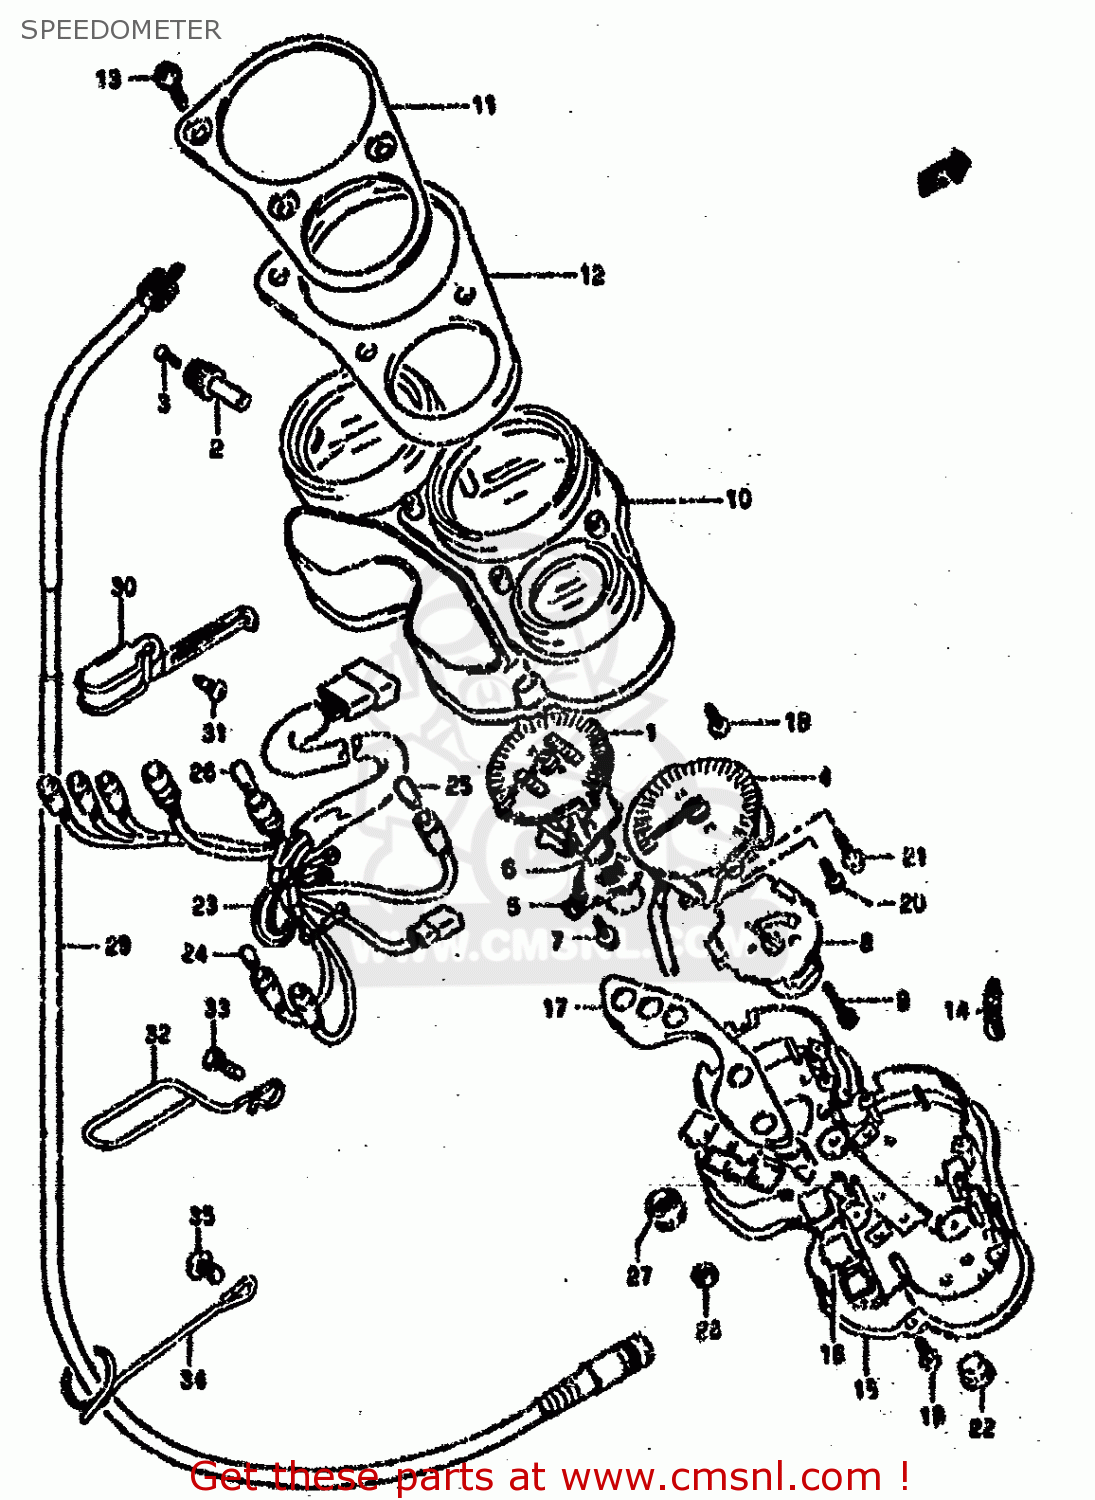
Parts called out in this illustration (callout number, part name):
1	SPEEDOMETER
2	KNOB,TRIP
3	ROTOR,SPEED
4	TACHOMETER
5	GEAR BOX,SPEEDOMETER
6	O RING
7	SCREW
8	METER,TEMPERATURE
9	SCREW(3X22)
10	HOOD
11	PANEL,METER
12	CUSHION
13	SCREW
14	CLAMP
15	CASE,METER
16	LENS SET
17	PANEL
18	SCREW
19	SCREW (3X10)
20	SCREW
21	SCREW(4X22)
22	CAP
23	SOCKET
24	BULB(12V3W,T6.5)
25	BULB(12V1.7W,T6.5)
26	BULB(12V1.7W,T10,WB121)
27	CUSHION,METER
28	NUT
29	CABLE ASSY,SPEEDOMETER
30	GUIDE,METER CABLE NO.1
31	SCREW 5X8
32	GUIDE,METER CABLE NO.2
33	SCREW
34	GUIDE,SPEEDOMETER CABLE,R
35	SCREW 6X10
